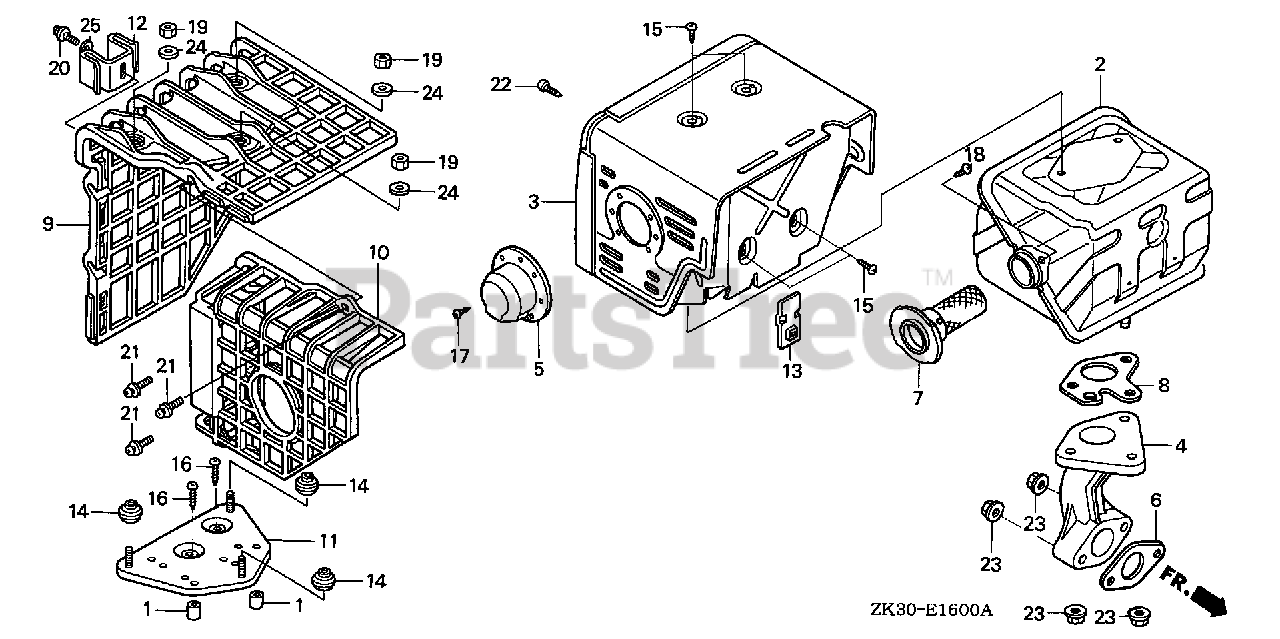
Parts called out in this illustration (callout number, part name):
2	MUFFLER (100DB)
3	PROTECTOR, MUFFLER
6	GASKET, EX. PIPE
7	ARRESTER, SPARK
8	GASKET, MUFFLER (ARRESTER) (NIPPON LEAKLESS)
15	SCREW, TAPPING (5X8)
18	SCREW, TAPPING (5X8)
22	SCREW, TAPPING (6X10)
23	NUT, FLANGE (8MM)
